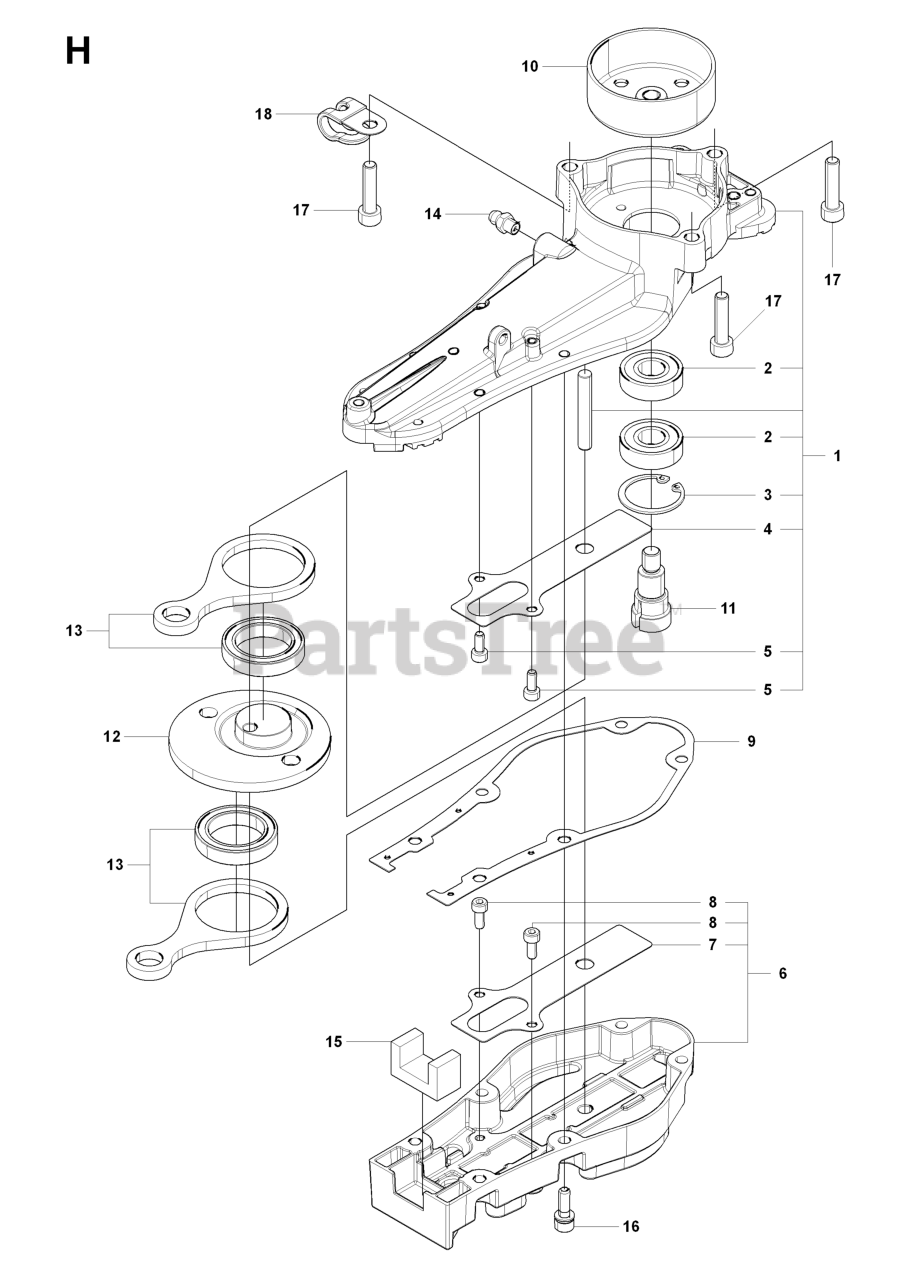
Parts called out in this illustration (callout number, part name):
1	GEARCASE COMPLETE UPPER
6	GEARCASE COMP. BOTTOM
11	GEAR DRIVE
12	GEAR DRIVE
14	FITTING
18	CLAMP
